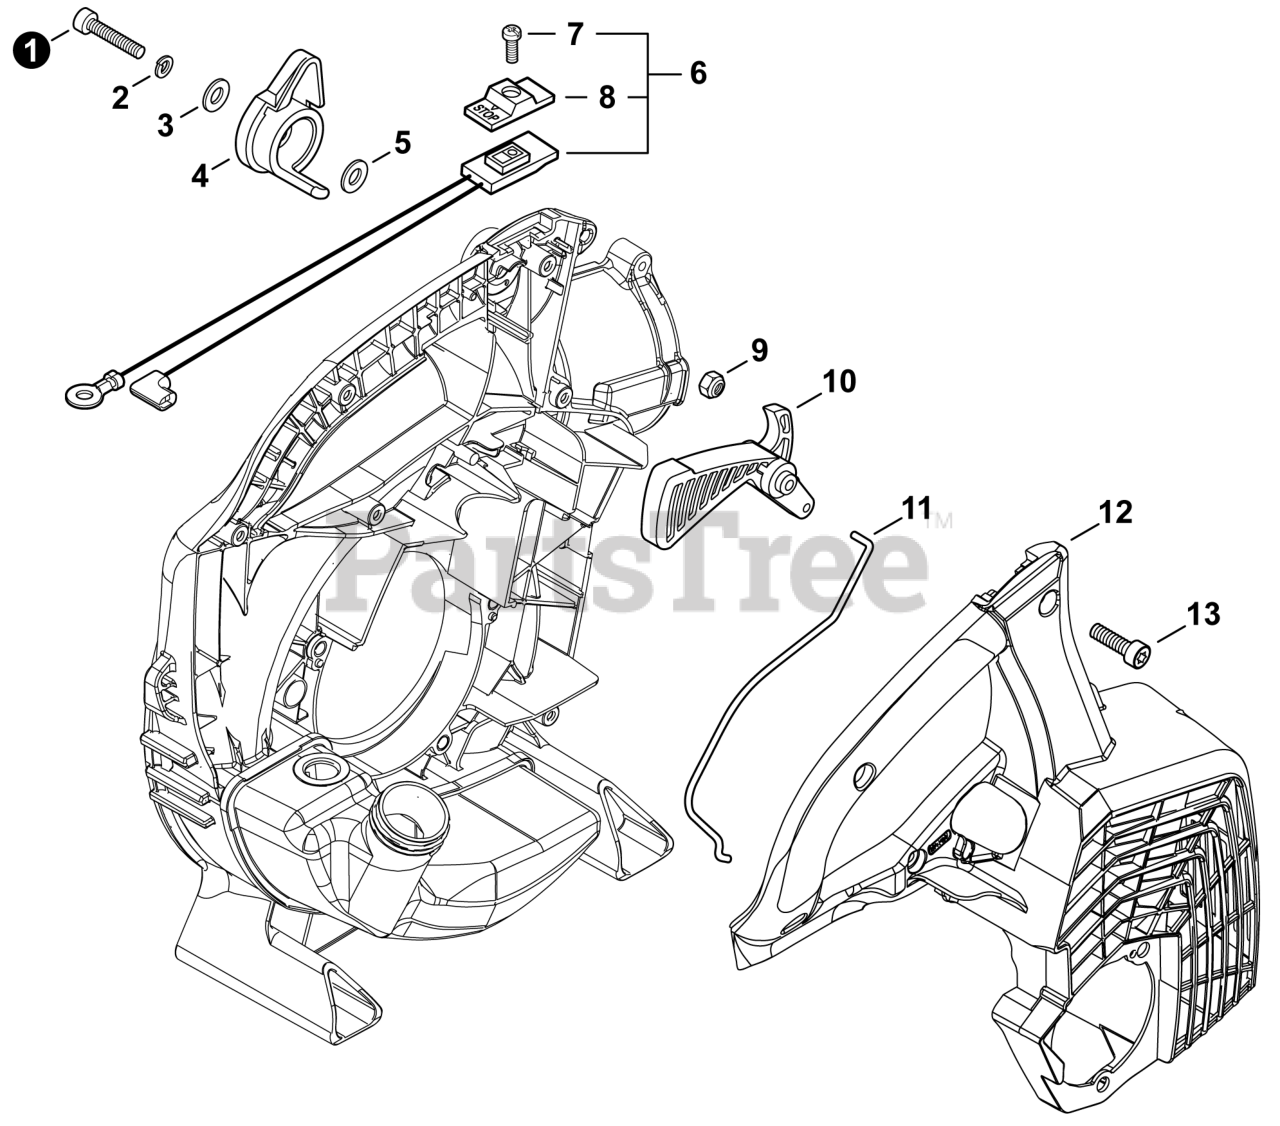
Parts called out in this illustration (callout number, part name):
1	BOLT, TORX 5x25
2	WASHER, SPRING 5
3	WASHER 5.5x12x0.8
4	CONTROL, THROTTLE
5	WASHER 5.5x12x0.8
6	SWITCH, ON-OFF
7	SCREW 3x10
8	KNOB, SWITCH
9	NUT, LOCK M5
10	TRIGGER, THROTTLE
11	ROD, THROTTLE
12	COVER, ENGINE
13	BOLT, TORX 5x20
